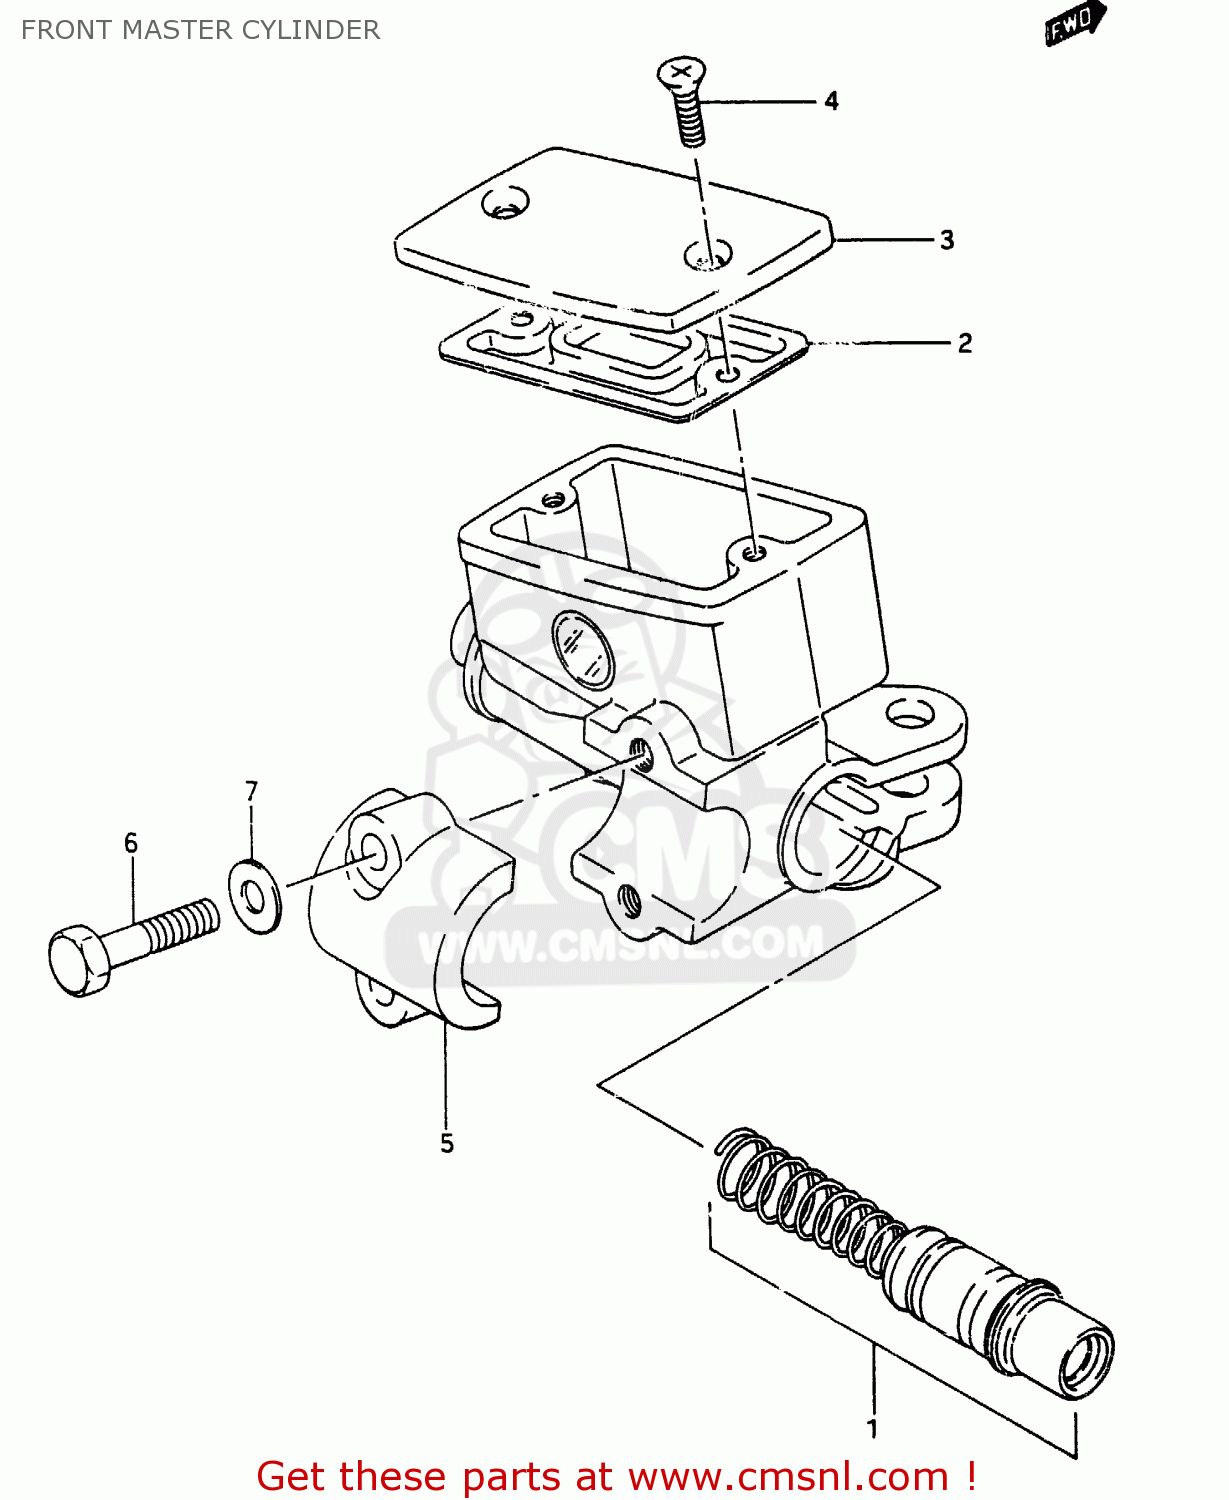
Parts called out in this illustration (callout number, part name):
1	PISTON & CUP SET
2	3
3	CAP
4	SCREW
5	HOLDER,MASTER CYLINDER
6	BOLT
7	WASHER
